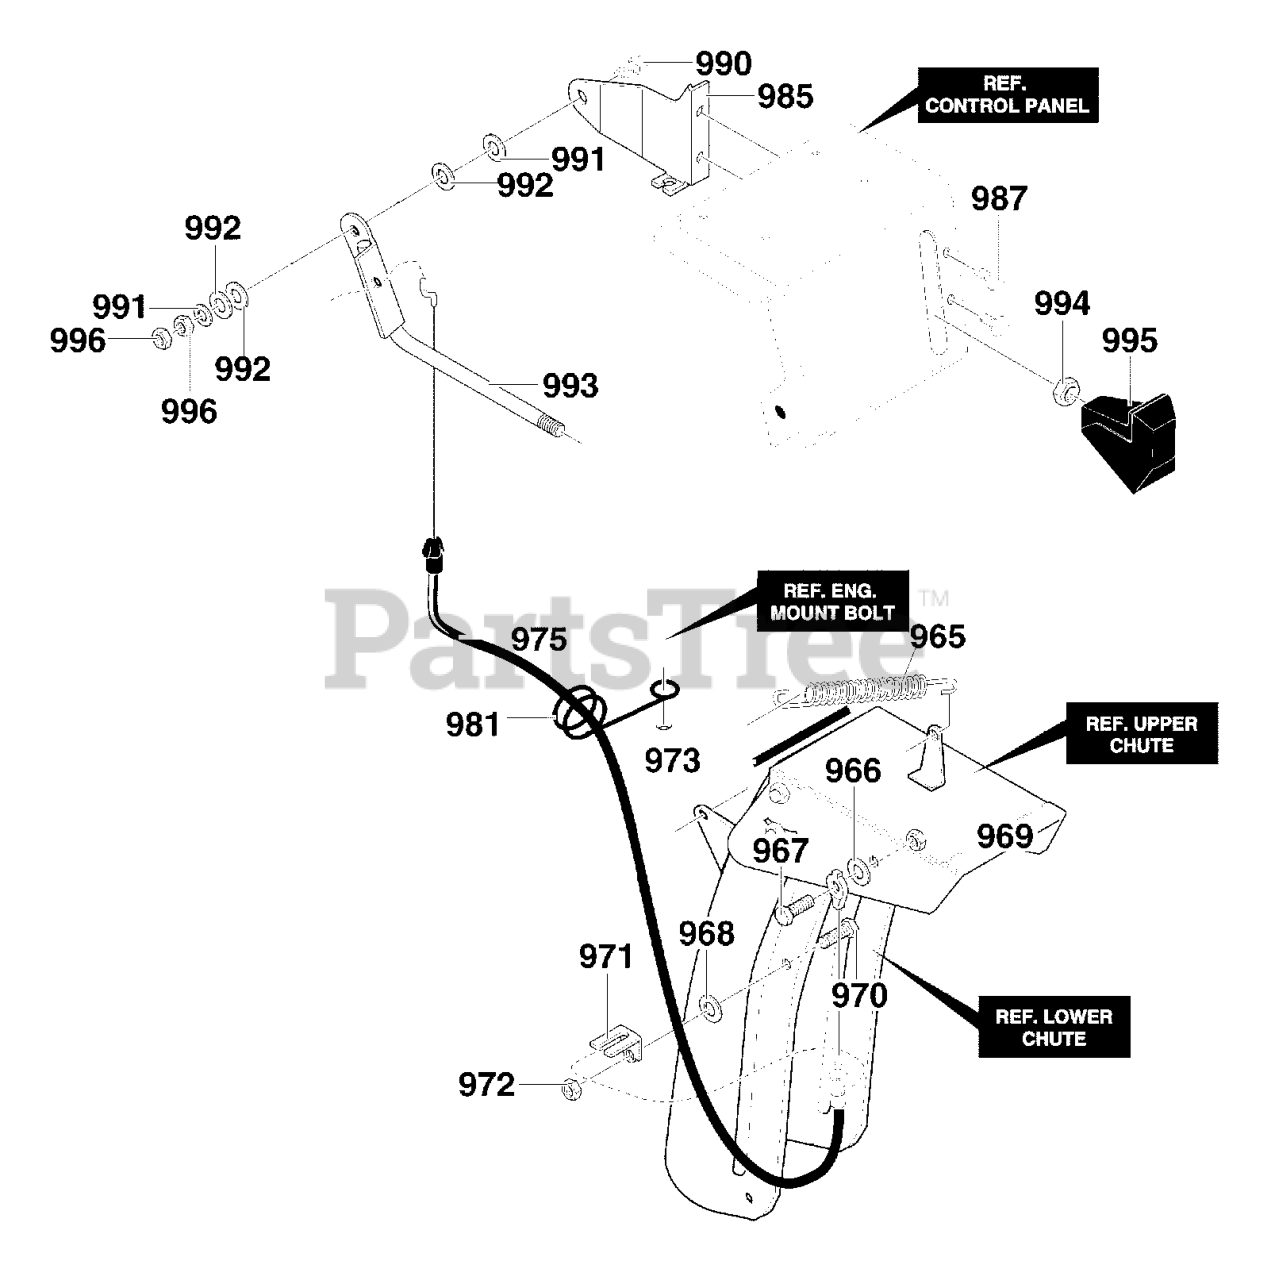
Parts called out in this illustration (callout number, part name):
965	TENSION SPRING
966	FLATWASHER
968	FLATWASHER
971	BRACKET, CABLE CHUTE
973	TRIM STRIP, BLACK
975	CABLE, CHUTE DEFLECTOR
981	WIRE FORM, REMOTE CHUTE CABLE
985	BRACKET, SNAP-IN REMOTE
987	SCREW
991	WASHER, FLAT
992	WASHER, SPRING
993	HANDLE, ASSY
995	KNOB, SHIFT
996	NUT
